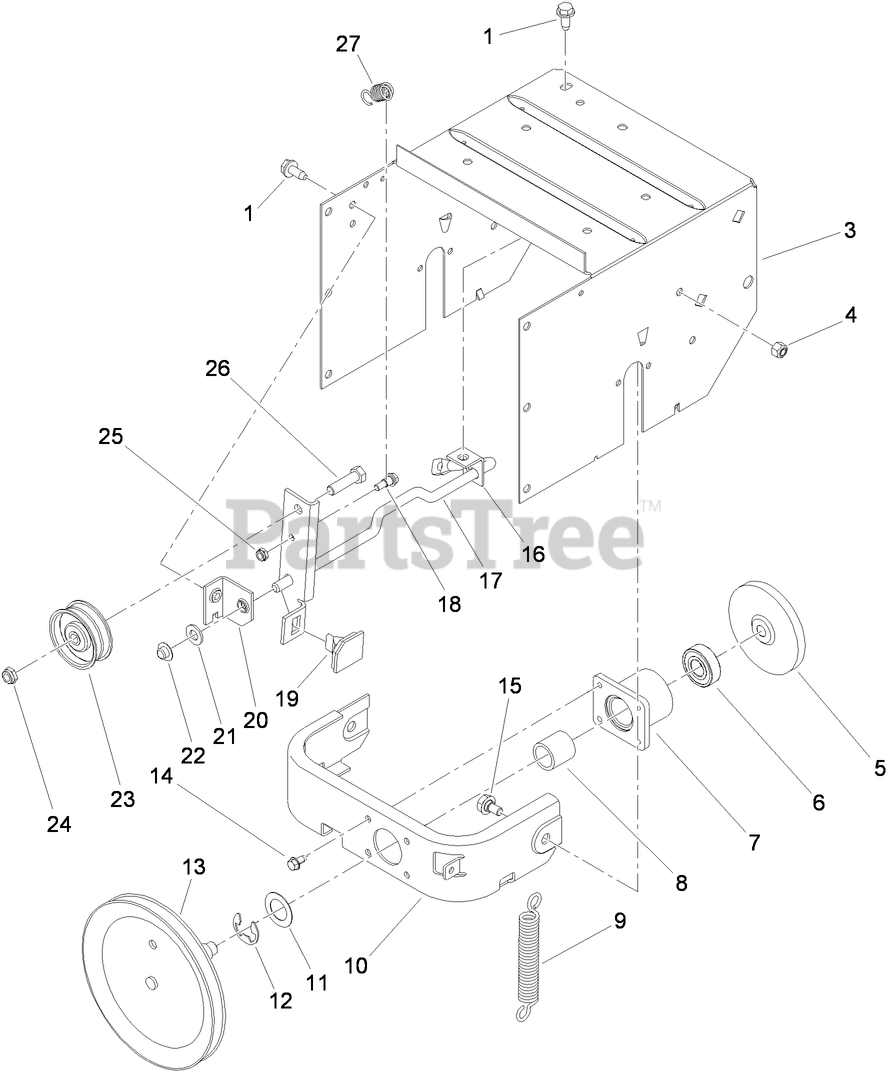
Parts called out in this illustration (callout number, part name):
1	SCREW-HWHTF
3	FRAME-TRACTION
4	NUT-LOCK, NI
5	PLATE-FRICTION
7	HUB-FRAME, TRACTION
8	BUSHING
9	SPRING-PLATE, FRICTION
10	FRAME-FRONT
11	WASHER-THRUST
12	RING-RETAINING, EXT
13	PULLEY AND DRIVE ASM
14	SCREW-HWH
15	BOLT-SHOULDER
16	BRACKET-MOUNT, REAR
17	AUGER CLUTCH ROD ASM
18	BOLT-SHOULDER
19	PAD-BRAKE
20	BRACKET-MOUNT, FRONT
21	WASHER-FLAT
22	NUT-PUSH
23	PULLEY-IDLER
25	NUT-LOCK, NI
26	SCREW-HH
27	SPRING
